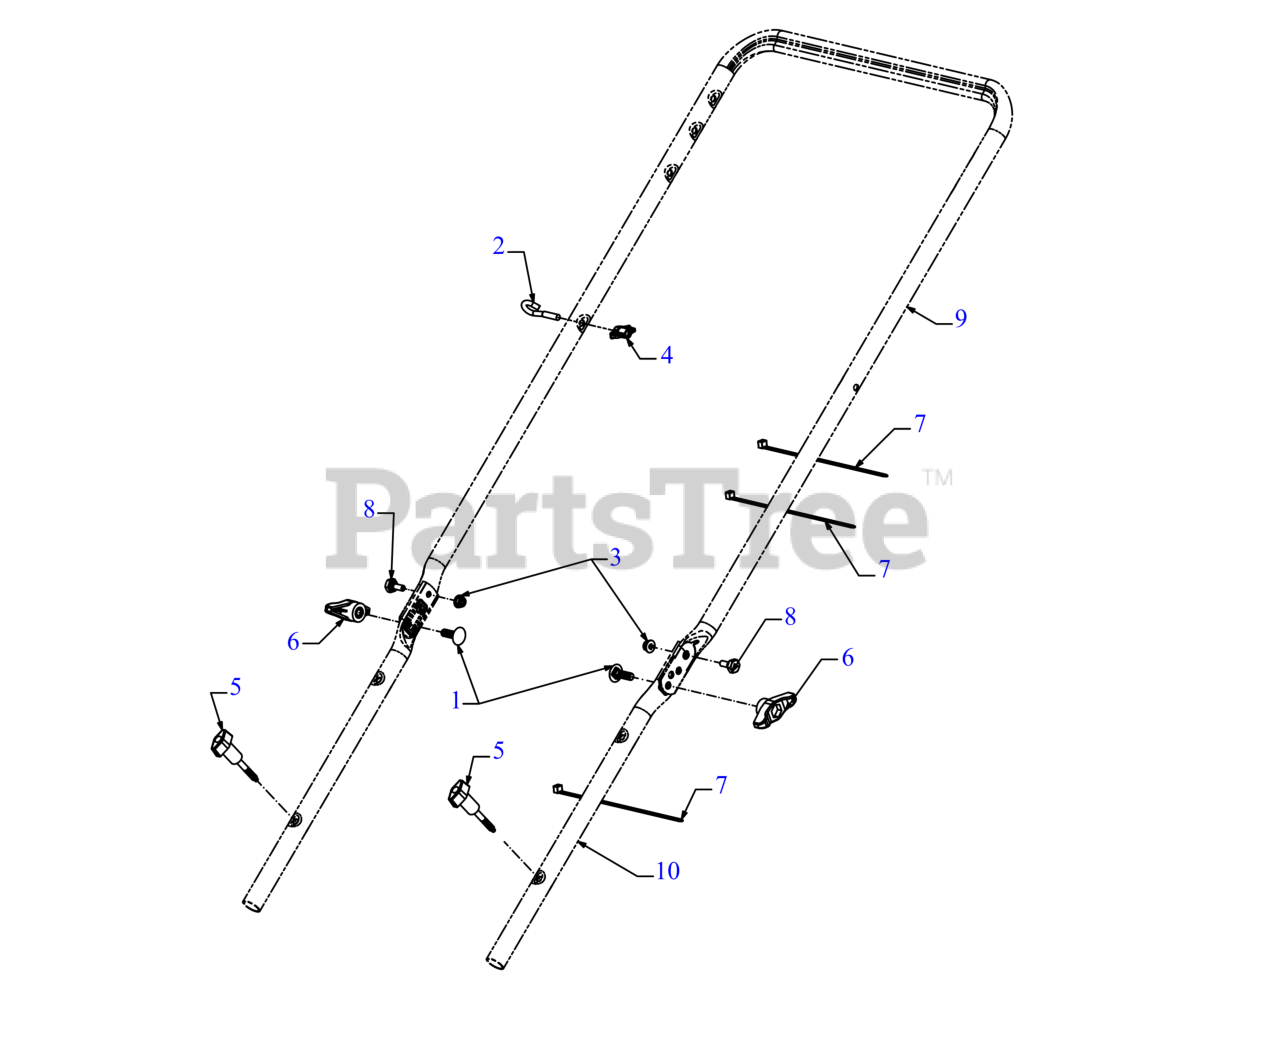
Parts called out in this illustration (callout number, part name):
1	SCREW 5/16-18 x 1.00 GR5
2	EYEBOLT 1/4-20
3	FLANGE LOCK NUT
4	HANDLE KNOB
5	WING KNOB 1/4-20
6	WING KNOB 5/16-18
7	7" CABLE TIE
8	SHOULDER SCREW
9	UPPER ERGO HANDLE
10	LOWER HANDLE (EZ FOLD)
